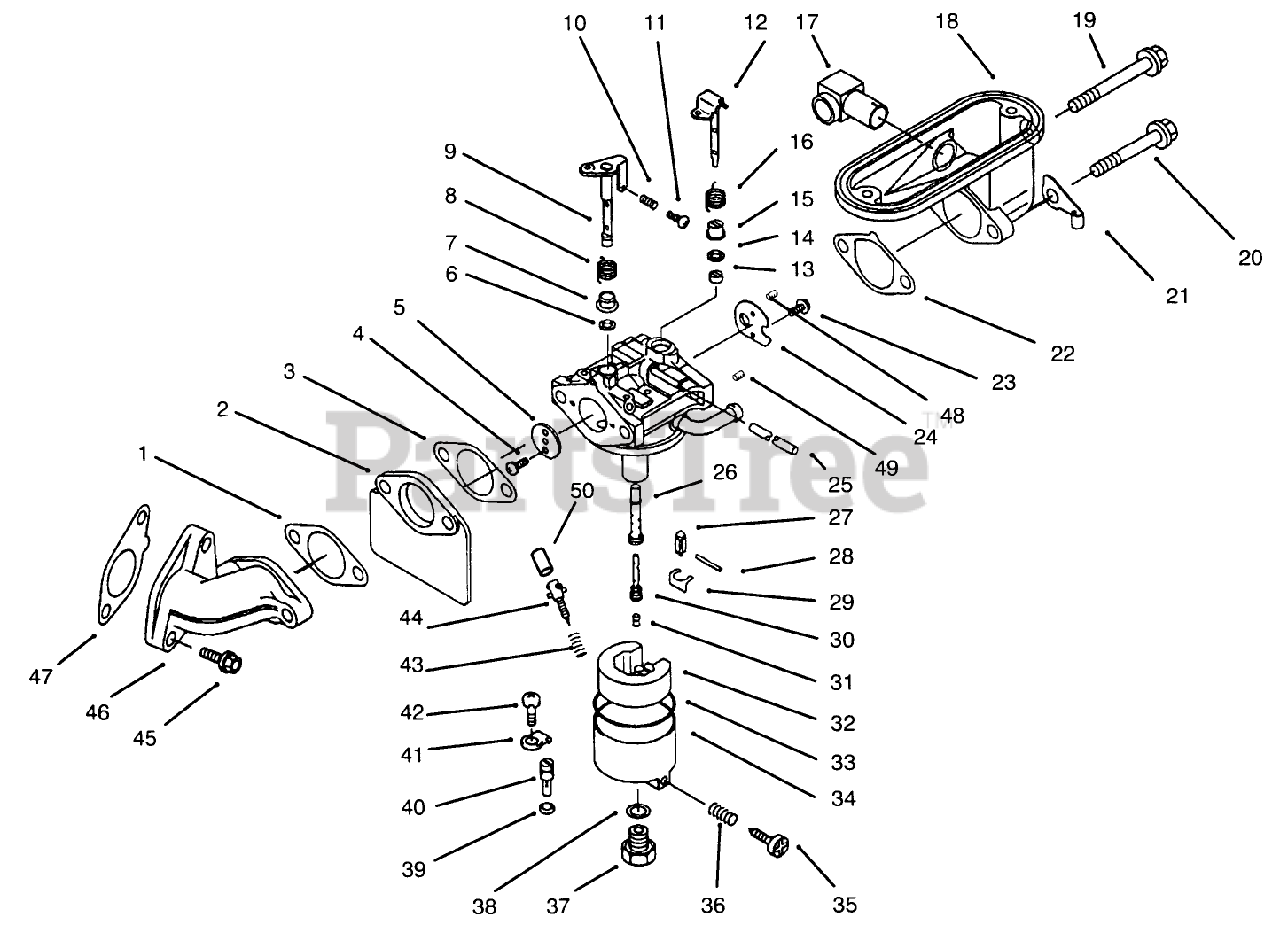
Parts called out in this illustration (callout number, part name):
1	Gasket
2	Insulator
3	Gasket-Carburetor
4	Screw
5	Valve-Throttle #110
6	Seal
7	Collar
8	Spring
9	Shaft-Throttle
10	Spring
11	Screw
12	Shaft-Choke
13	Collar
14	Seal
15	Ring
16	Spring
17	Joint
18	Pipe-Intake
19	Bolt
20	Bolt
21	Clamp
22	Gasket
23	Screw
24	Valve-Choke
25	Tube
26	Nozzle-Main
27	Valve-Float
28	Pin
29	Ring-Snap
30	Holder-Main Jet
31	Jet-Main
32	Float
33	Gasket
34	Chamber-Float (Incl. Ref. #35, 36)
35	Screw
36	Spring
37	Bolt
38	Gasket
39	Gasket
40	Jet-Pilot
41	Plate
42	Screw
43	Spring
44	Screw-Pilot Air
45	Bolt-Flanged (8X25)
46	Pipe-Intake
47	Gasket-Intake Pipe
48	Jet-Air #0.9
49	Jet-Air #1.4
50	Limiter
